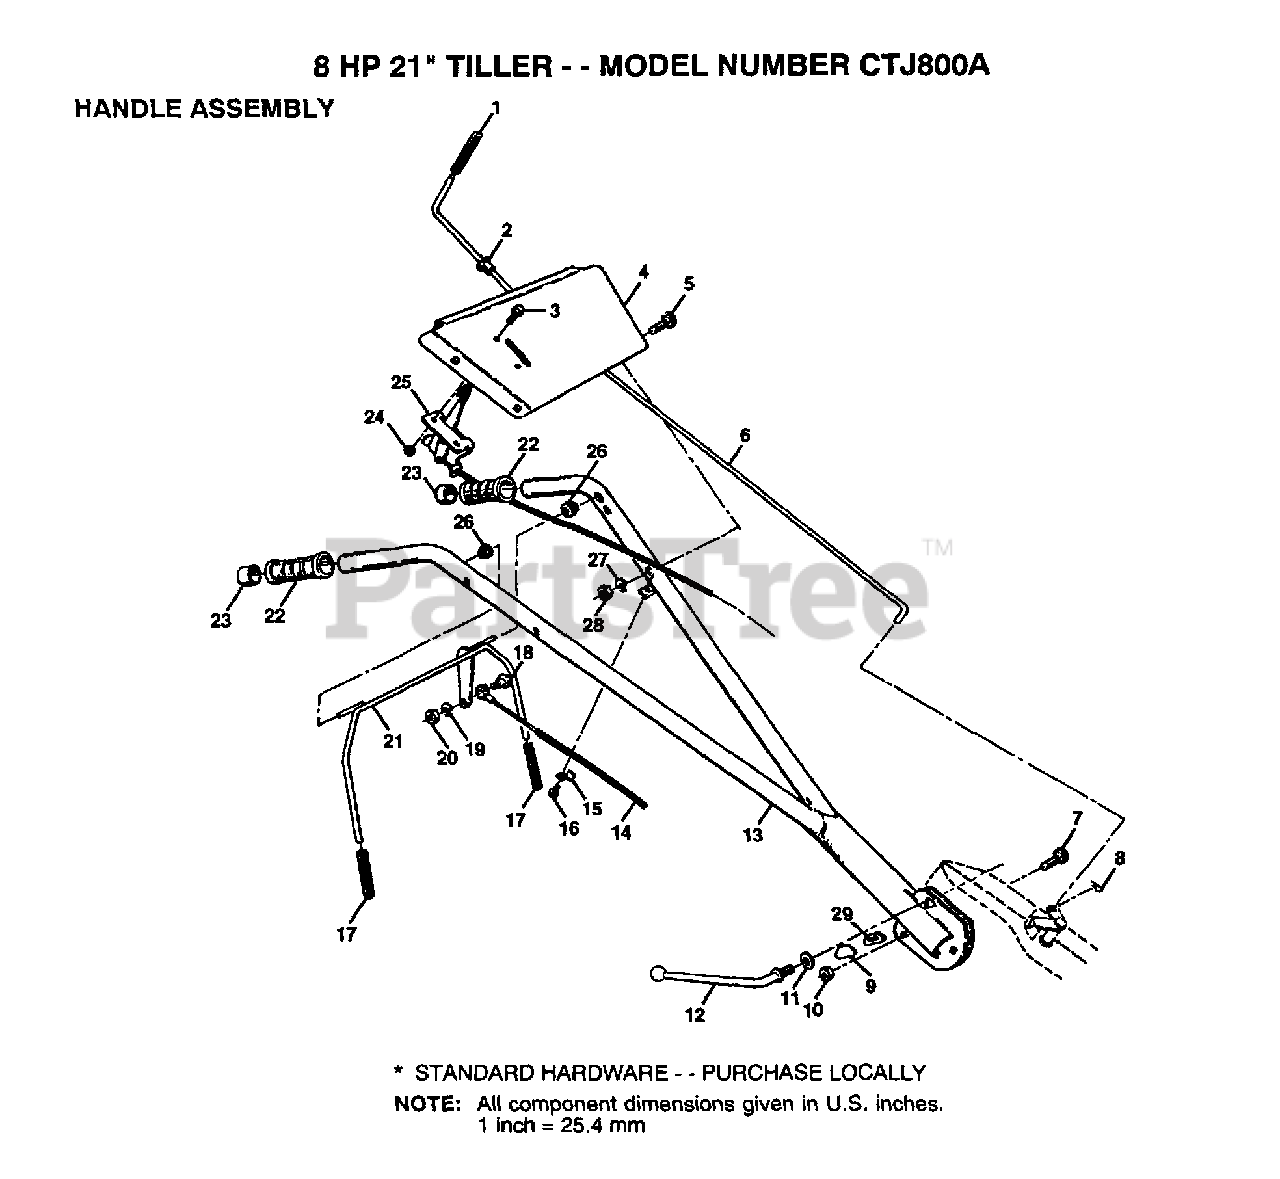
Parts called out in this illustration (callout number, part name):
1	GRIP TI
2	BUSHING
3	SCREW
5	BOLT CARRIAGE CRT
6	ROD SHIFT CRT
7	BOLT D
8	RETAINER M
9	LOCK CRT
10	LOCKNUT
11	WASHER CRT
12	LEVER LOCK CRT
14	CABLE-CLUTCH CRT
15	CONDIUT CLIP T
17	GRIP BAR CRT
18	SHOULDER BOLT ST
19	LOCKWASHER
21	HANDLE BAR CRT
23	CAP CRT
25	CONTROL.THROTTLE
27	LOCKWASHER
29	LOCK.HANDLE
